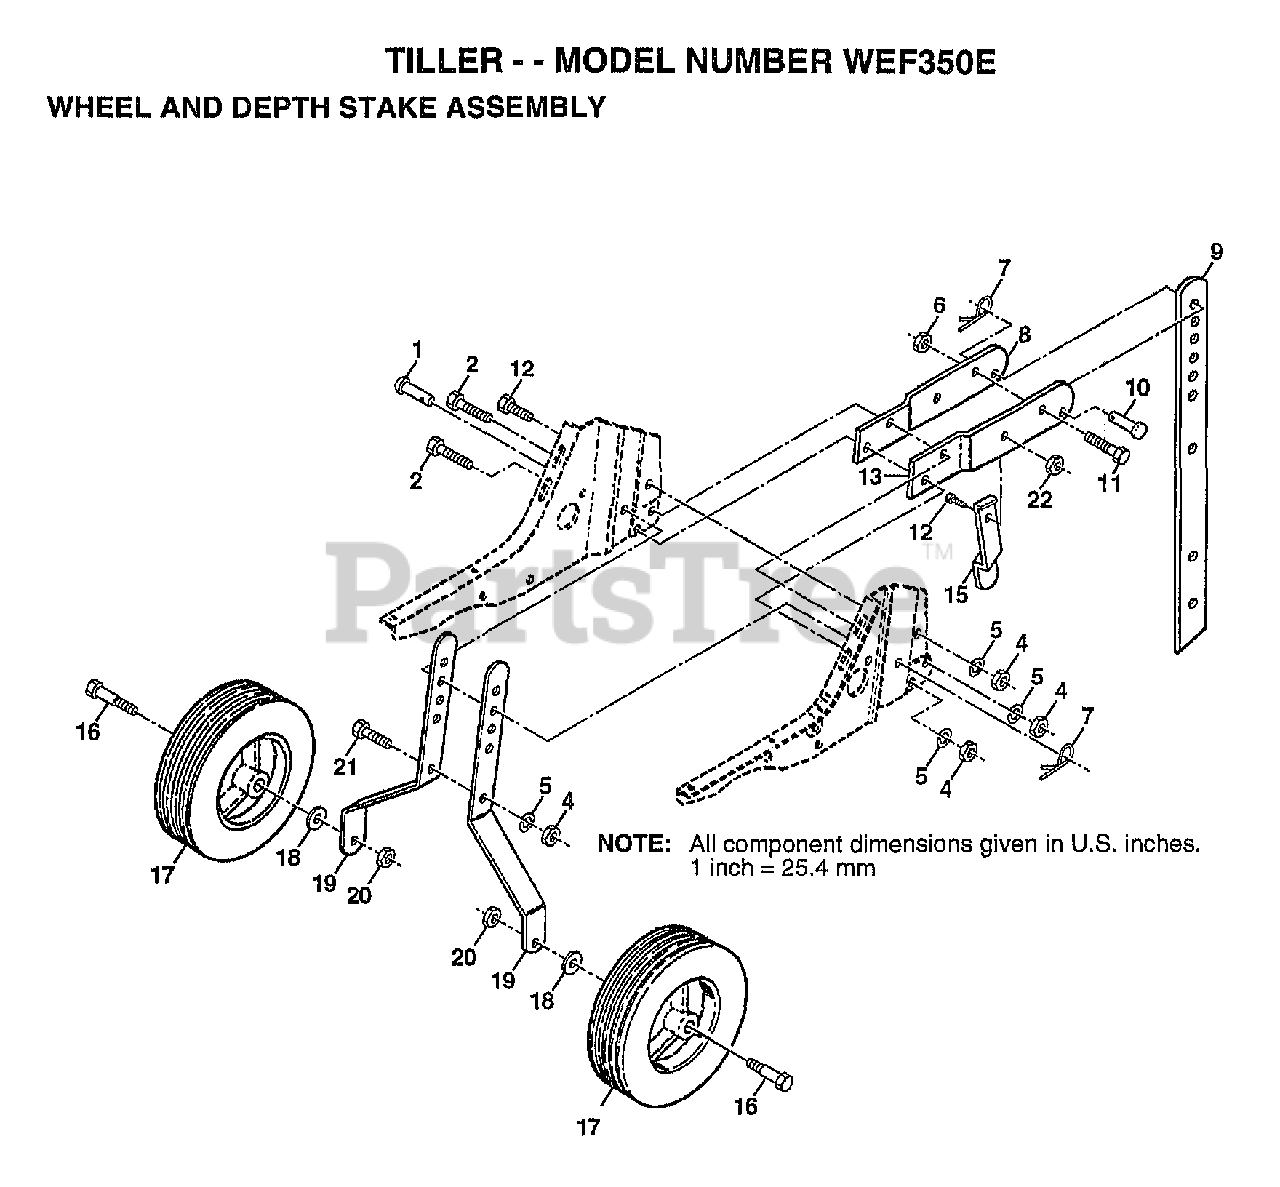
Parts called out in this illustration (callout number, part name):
1	DRILLED RIVET RT
4	NUT.HEX.5/16-18
5	LOCKWASHER
6	NUT
7	SPRING.RETAINER
8	STAKE.SUPT.TILLER
10	DRILLED RIVET RT
11	BOLT.HEX.5/16-1.5
12	BOLT
15	STAKE SPRING TI
16	BOLT SHOULDER
18	WASHER
22	NUT
